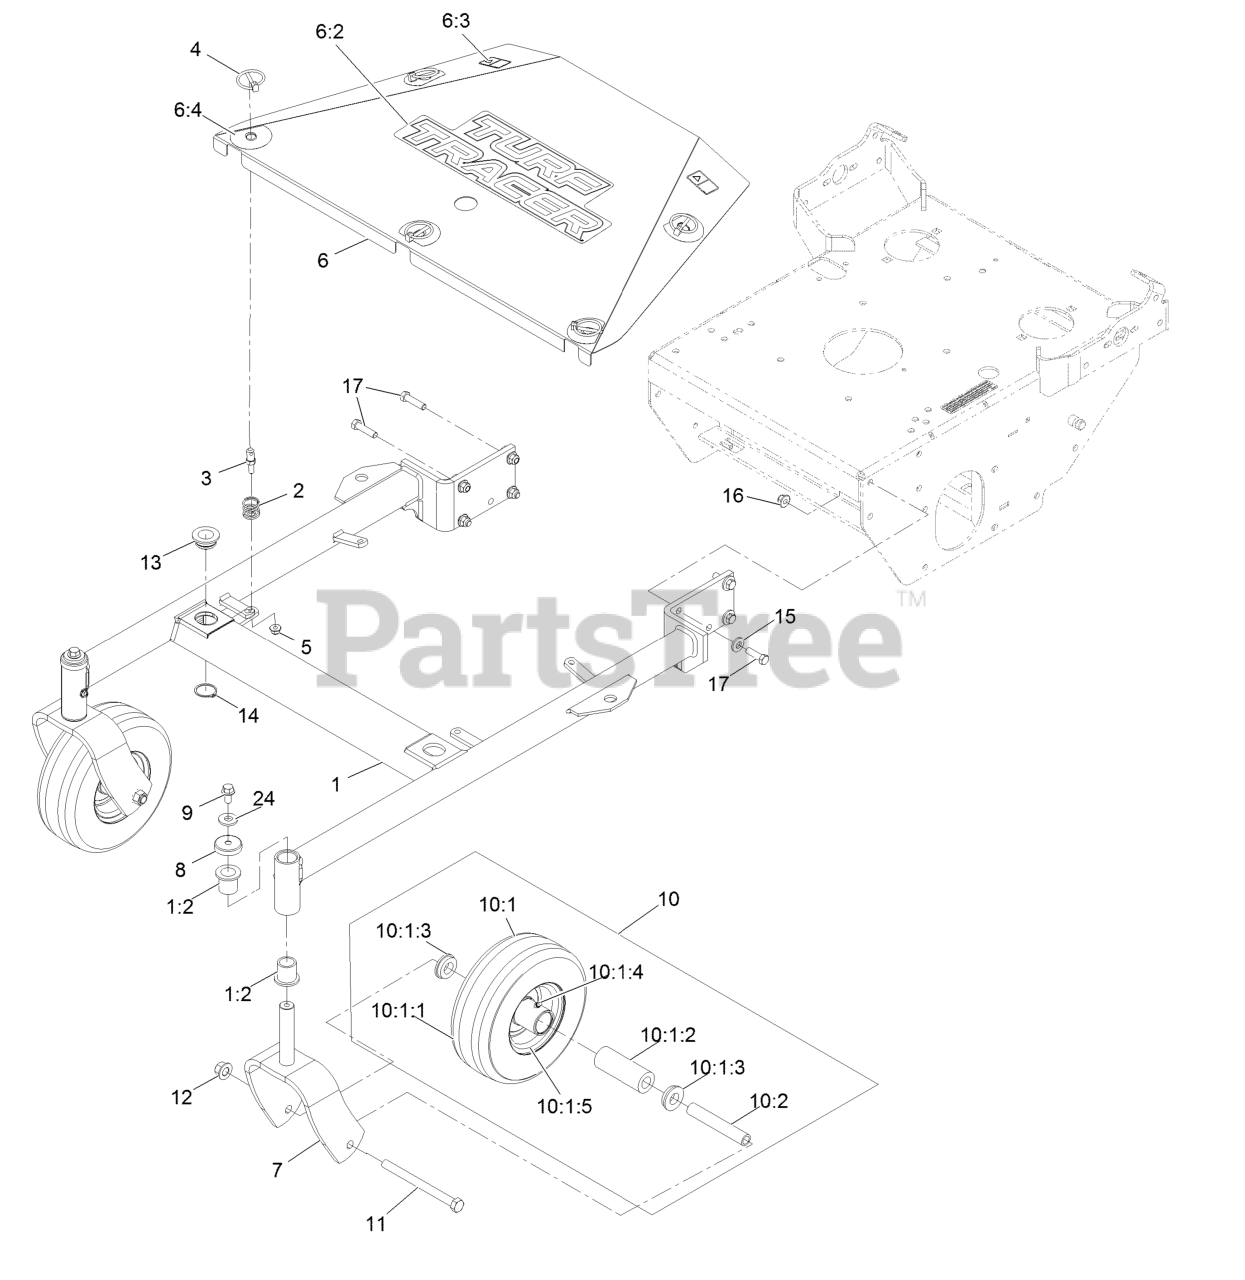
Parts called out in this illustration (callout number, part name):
1	ASM, Frame W/ Bushings, 36
1:2	Bearing-Flanged
3	Pin-Spring
4	Pin-Lynch
5	Nut-Nyloc 5/16-18 Flg
6	ASM, Shield W/ Decals, 36
6:2	Decal-Turf Tracer
6:3	Decal-Warning
6:4	Decal-Scratch Cover
7	Fork, Caster [red]
8	Cap, Dust
9	Screw-Hex Flange 3/8-16 X 3/4
10	Kit,Semi-Pneumatic Wheel Replacement
10:1	Wheel And Tire ASM
10:1:1	Tire
10:1:2	Bearing
10:1:3	Bushing-Flanged
10:1:4	Zerk-45deg 1/4-28
10:1:5	Wheel
11	Screw-HH 1/2-13 X 6
12	Nut-Lock 1/2-13
13	Bushing-Deck
14	Ring-Retaining
15	Washer-Spring Disc 3/8
16	Nut-Nyloc 3/8-16 Flg
17	Screw-HH 3/8-16 X 1 1/4
